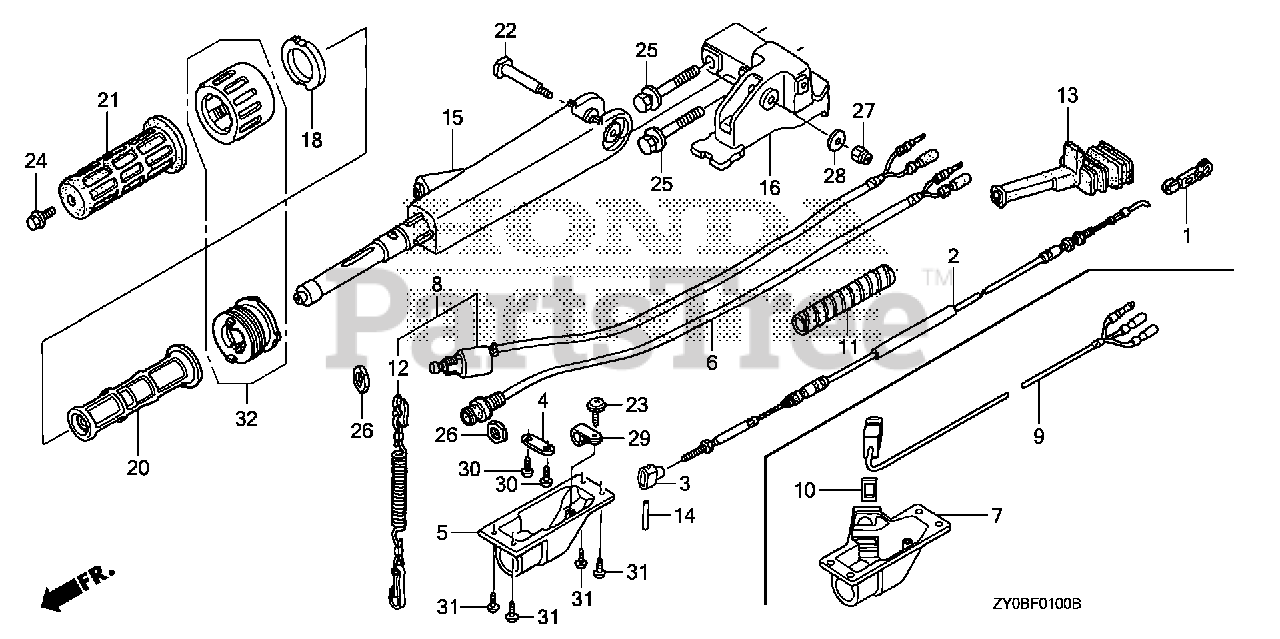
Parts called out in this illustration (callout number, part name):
1	LINKAGE, PIVOT
2	CABLE, THROTTLE
3	PIVOT, THROTTLE CABLE
4	PLATE, SHIFT
6	SWITCH ASSY., STARTER
7	COVER, SWITCH (PT)
8	SWITCH ASSY., EMERGENCY STOP
9	SWITCH ASSY., POWER TILT
10	STAY, POWER TILT SWITCH
11	TUBE, SPIRAL B
12	WIRE, EMERGENCY (SINGLE) (DUAL)
13	GROMMET, OIL CASE (A)
14	PIN, THROTTLE CABLE
15	HANDLEBAR *NH246* (LOOSY GRAY)
16	BRACKET, HANDLEBAR *NH246* (LOOSY GRAY)
18	PAD, THROTTLE FRICTION
20	PIPE, GRIP
21	RUBBER, GRIP
22	SCREW, HANDLE PIVOT
23	SCREW, TAPPING (4X10)
24	BOLT, FLANGE (6X12) Use from Frame SN 1005249.
25	BOLT-WASHER (10X55)
26	NUT, HEX. (16MM) DUAL QTY = (2) (SINGLE)
27	NUT, SELF-LOCK (8MM)
28	WASHER (8MM)
29	CLIP, WIRE HARNESS (6.3MM)
30	SCREW, TAPPING (4X12)
31	SCREW, TAPPING (4X12)
32	GRIP ASSY., THROTTLE FRICTION
32	GRIP, THROTTLE FRICTION (FOR U.S.A.)(COO)
